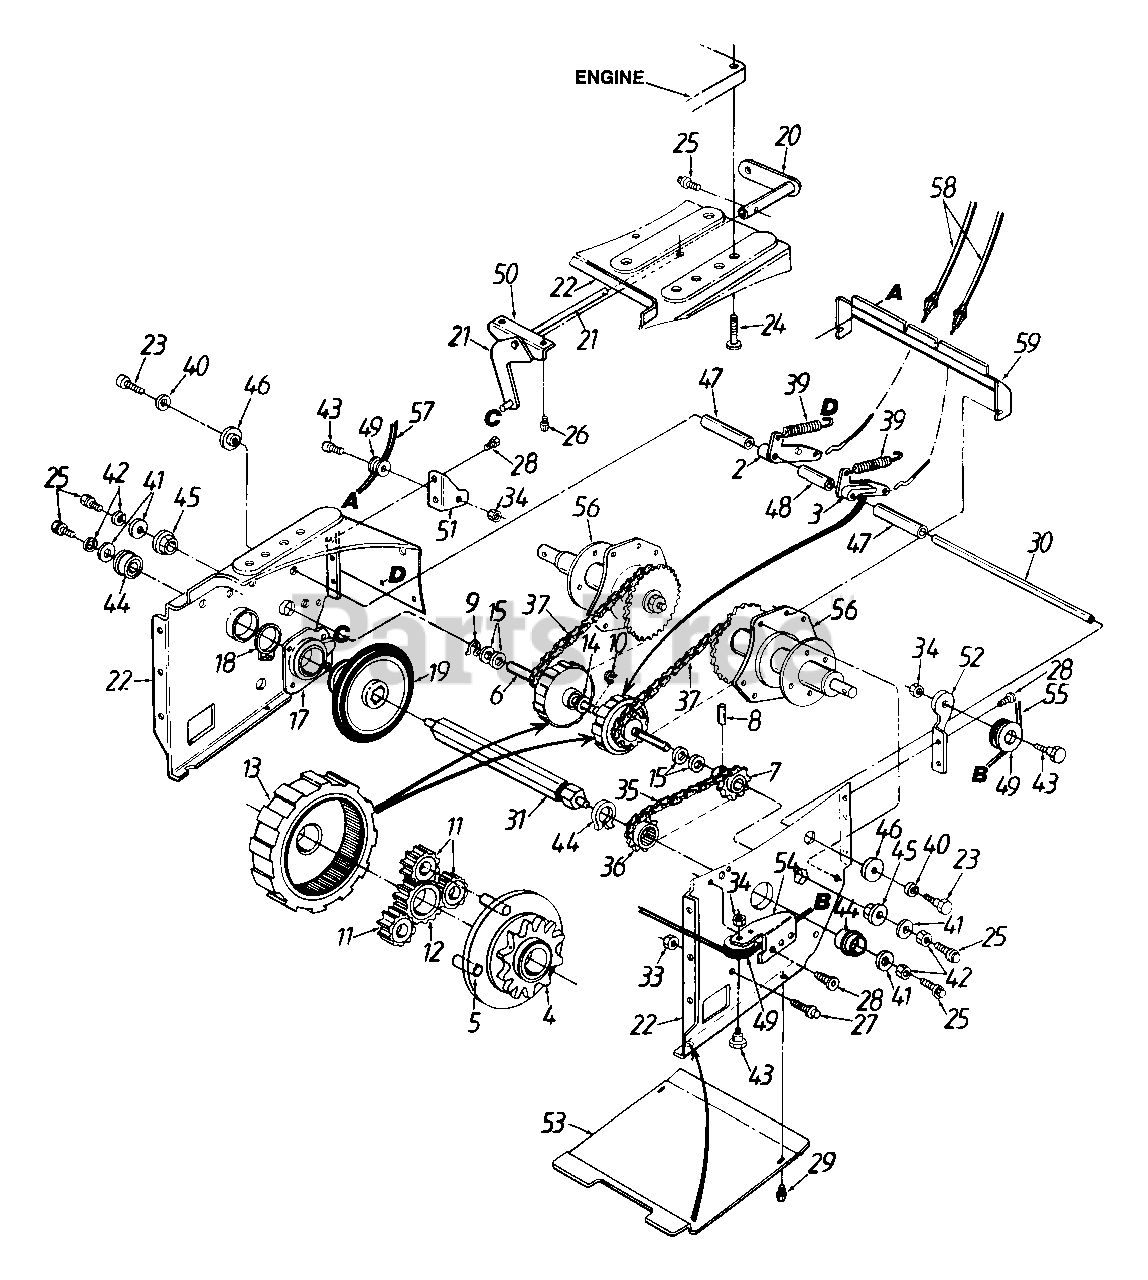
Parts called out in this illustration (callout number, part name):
2	R.H. Dog Ass'y.
3	L.H. Dog Ass'y.
4	Carrier
5	5/16" Dowel Pin
6	Drive Shaft
7	12 Tooth Sprocket
8	Spring Pin 3/16" Dia. x 1" Lg.
9	Snap Ring .56" Dia.
10	Snap Ring .625" Shaft
11	12 Tooth Gear
12	18 Tooth Gear
13	Ring Gear
14	Fl-Wash. 5/8" I.D. x 1" O.D.
15	Fl-Wash..57" I.D. x 1.12" O.D.
17	Friction Wheel Brg. Ass'y.
18	Retaining Ring 1.375" Dia. Shaft
19	Friction Wheel
21	Shift Rod Ass'y.
23	Hex Bolt 5/16-18 x .75" Lg.
24	Hex L-Wash. TT-Tap Scr. 3/8-16 x 1.25" Lg.
25	Hex TT-Tap Scr. 1/4-20 x .75" Lg.
26	Hex Wash. Hd. Tap Scr. 1/4-20 x .38" Lg.
27	Hex Wash. TT-Tap Scr. 1/4-20 x 1" Lg.
28	Torx Mach. AB-Tap Scr. 1/4 x .62" Lg.
29	Hex Wash. Hd. Tap Scr. #12 x .38" Lg.
30	Actuator Shaft
31	Drive Shaft
33	Hex Nut 1/4-20 Thd.
34	Hex Jam Nut 1/4-20 Thd.
35	#420 Chain - 1/2 Pitch x 30 Link (Endless)
36	11 Tooth Sprocket
37	#420 Chain - 32 Links (Endless)
39	Extension Spring 2.03" Lg.
40	L-Wash. 5/16" I.D.
41	Fl-Wash. 1/4" I.D. x .93" O.D.
42	L-Wash. 1/4" I.D.
43	Shld. Bolt 5/16" Dia. x .35" Lg.
44	Ball Brg. w/Snap Ring
45	Hex Flange Bearing
46	Shld. Spacer .5" Dia. x .27" Lg.
47	Split Shld. Spacer 2.69" Lg.
48	Split Shld. Spacer 1.77" Lg.
49	Cable Roller
56	Track Hub Ass'y.
57	Drive Clutch Cable
58	Track Steer Cable w/Trigger
